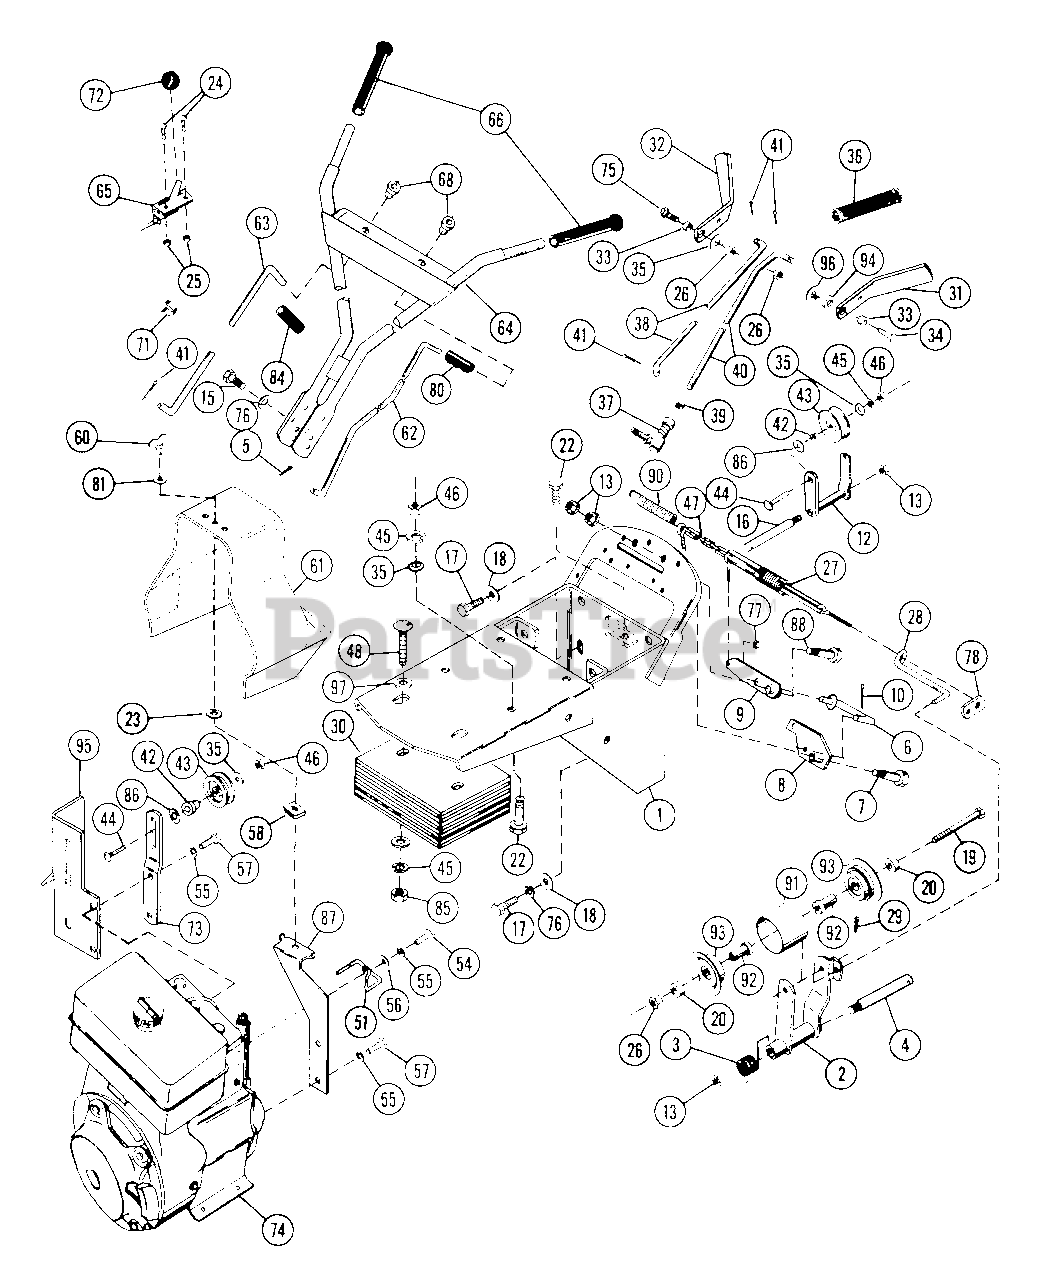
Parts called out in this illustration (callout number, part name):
2	IDLER ARM
3	SG-TORS .076X.89X1.98
4	IDLER PIN
5	PIN-COTR .12X1.0 PL
6	CLUTCH LINK
7	SHOULDER BOLT
8	CLUTCH BELLCRANK
9	SPRING ARM
10	PIN-COTR .09X1.0 PL
11	NUT-LK-CTR .375-16 GR A PL
12	IDLER ARM
13	NUT-LK-FLG .375-16 PL
14	SHOULDER BOLT
15	BLT-HEX .38-16X1.00 PL
16	IDLER PIN
17	BLT-HEX .38-16X1.25 PL GR 2
18	WSHR-FL-STL.406X.812X.065PL
19	BLT-HEX .31-18X3.75 PL GR2
20	BSHG, SPCR.500X.750X.321 PM
22	SCR-TAP .312-18X.75 HWH PL TR
23	NUT-RETNR
24	SCR-MCH 10-24X.50 SLRH PL
25	NUT-KEPS 10-24 PL
26	NUT-LK .312-18 GR A PL
27	CLUTCH SPRING
28	CLUTCH LINK
29	PIN-HAIR INT .06X.18X.77
30	WEIGHT WAFER
31	DRIVE CLUTCH HANDLE
32	TILLER CLUTCH HANDLE
33	SPACER BUSHING .5 X .32 X .21
34	BLT-HEX .31-18X.75 PL GR2
35	WSHR-FL-STL .38X.875X.083 PL
37	SNAP IN BALL JOINT
38	DRIVE CLUTCH ROD
39	NUT-HEX .312-24 PL
40	TILLER CLUTCH ROD
41	PIN-COTR .09X.75 PL
42	SPCR, BRG .315X.50X.688X.281
43	IDLER
44	BLT-RDHDSQNK .31-18X1.38SHT PL
45	WSHR-LK .312X.097 PL HVY
46	NUT-HEX .312-18
47	CLUTCH CHAIN
48	BLT-RDHDSQNK .38-16X1.50 PL
51	BELT FINGER
54	BLT-HEX .31-24X1.00 PL GR5
55	WSHR-LK-INT .313X.030 PL
56	WSHR-LOCK M 6MM STD
57	BLT-HEX .31-24X.50 GR5
58	NUT-SPEED 1/4 TURN SOUTHCO
60	SCR-WING .25 TURN SOUTHCO
61	BELT COVER
62	CLUTCH ROD
63	POSITION ROD
64	HANDLEBAR
65	THROTTLE CONTROL
66	HANDLEGRIP
68	SNAP BUSHING
71	BUTTON BUMPER
72	KNOB, CONTROL-THROTTLE
73	REVERSE IDLER BRACKET
74	ENGINE
76	WSHR-LK .375X.115 HVY PL
77	NUT-LK 8-32 GR A PL
78	RETAINING NUT
79	CLUTCH ROD
80	GRIP
81	WSHR-FL-STL .250X.562X.049 PL
84	GRIP
85	NUT-HEX .375-16
86	BLADE, 21" MOWER
87	BELT COVER BRACKET
88	SHOULDER BOLT
89	PIN-COTR .06X.50
90	SG-TENS .039X.44X1.75 WLD 3.2
92	BEARING SPACER
94	SPACER
95	HEAT SHIELD
96	WSHR-FL-STL .344X1.375X.075 PL
97	WSHR-FL-STL .630X1.005X.062 PL
98	BLT-HEX .31-18X1.25 PL GR2
